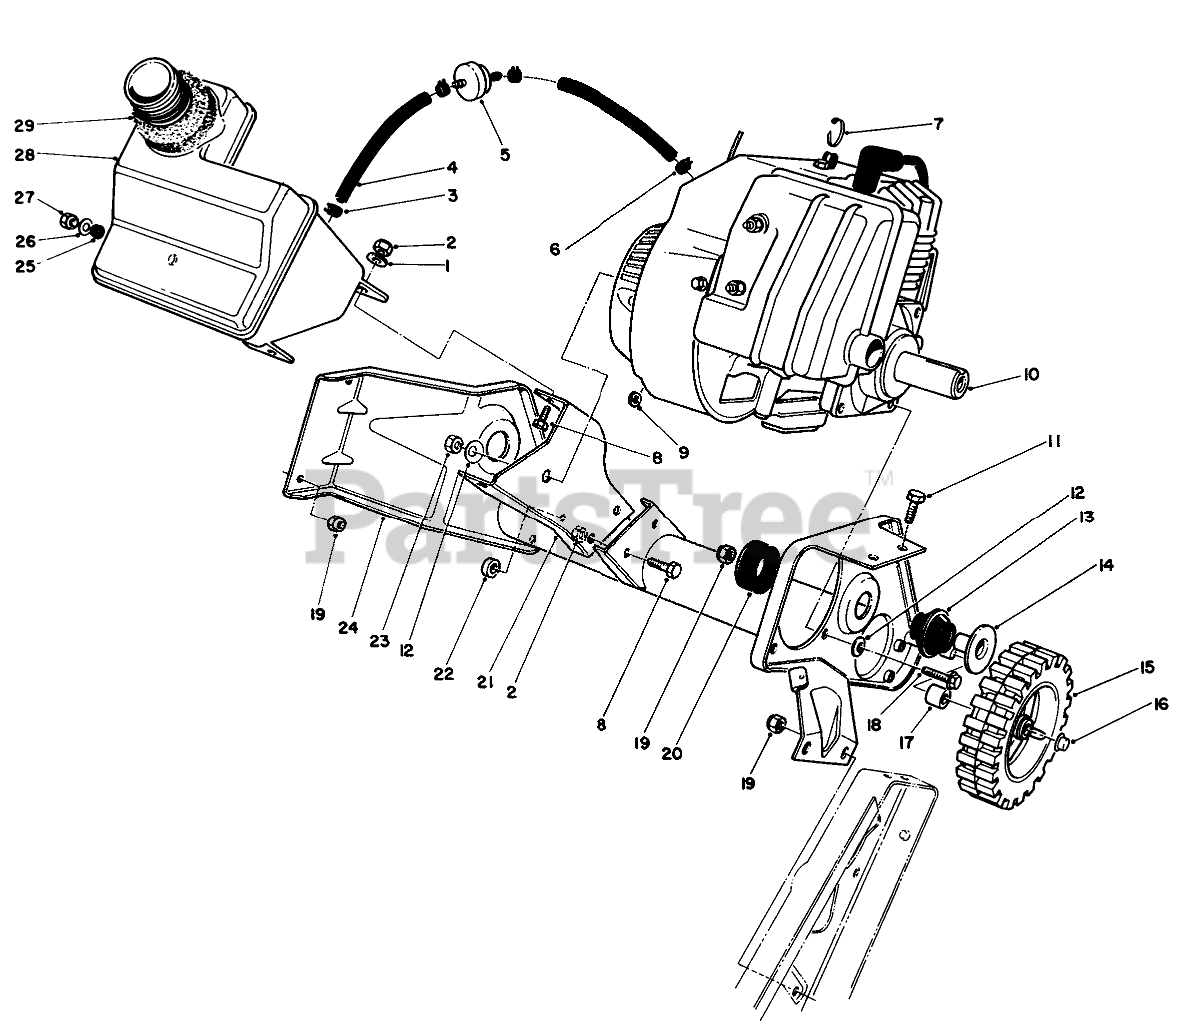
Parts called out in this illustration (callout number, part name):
1	WASHER-FLAT
2	NUT-LOCK, NI
3	Clamp
4	GAS LINE
5	FILTER-FUEL
6	CLAMP-HOSE
7	TIE-CABLE
8	SCREW-HH
9	SPACER-PLATE, PIVOT
10	Engine Assembly
11	SCREW-HH
12	WASHER-BELLEVILLE
13	MOUNT-REBOUND
14	SPACER TUBE
15	WHEEL
16	NUT-PUSH
17	SPACER-WHEEL
19	NUT-LOCK, NI
20	LOAD MOUNT
21	Support-Recoil
22	SPACER-WHEEL
23	NUT (F/W & PPP)
24	Wa-Frame
25	GROMMET-RUBBER
26	WASHER-PLAIN
27	NUT-LOCK, CONE
28	Tank-Fuel (Incl. Ref. #25)
29	SEAL-FOAM
